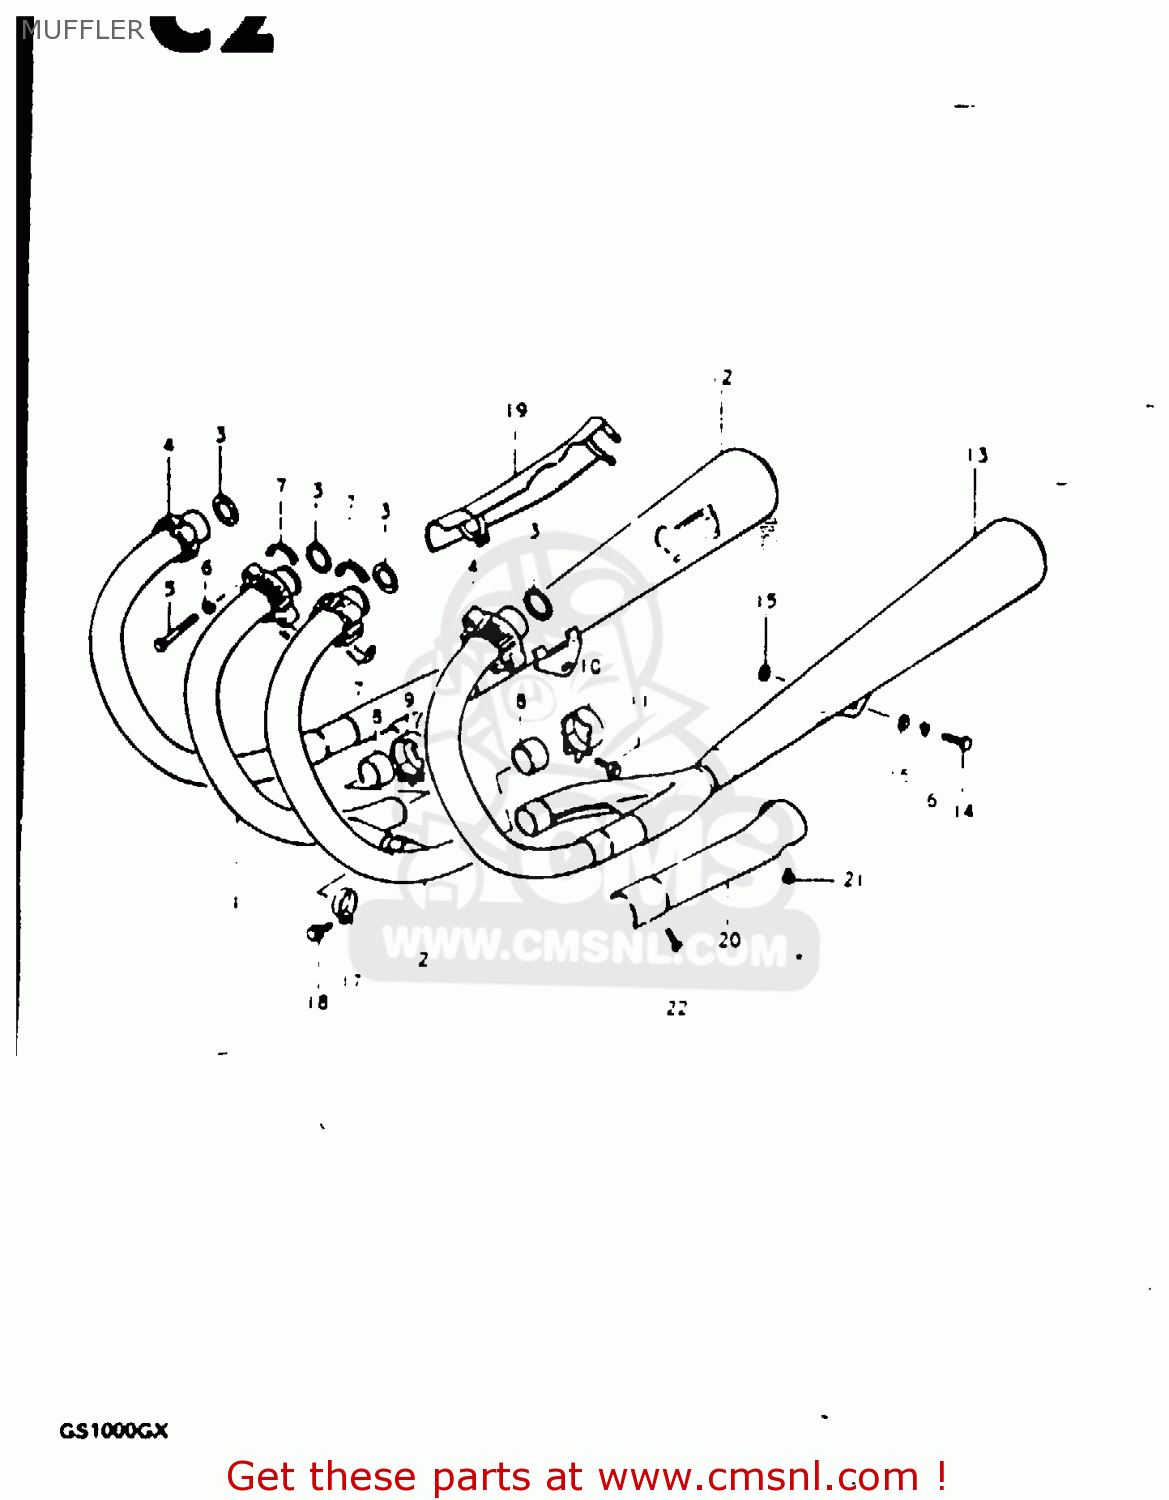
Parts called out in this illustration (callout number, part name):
1	PIPE,CENTER EXHAUST
2	COVER,EXHAUST PIPE
3	GASKET,EXHAUST PIPE (NAS)
4	CLAMP,EXHAUST PIPE
5	BOLT
6	7
7	PLATE,EXHAUST P
8	CONNECTOR,MUFFLER
9	CLAMP,MUFFLER CONNECTOR,R
10	CLAMP,MUFFLER CONNECTOR,L
11	BOLT
12	BODY,MUFFLER
13	BODY,MUFFLER
14	BOLT 10X30
15	WASHER
16	LOCK WASHER
17	CLAMP
18	BOLT
19	COVER,MUFFLER,R
20	COVER,MUFFLER
21	SCREW
22	SCREW
